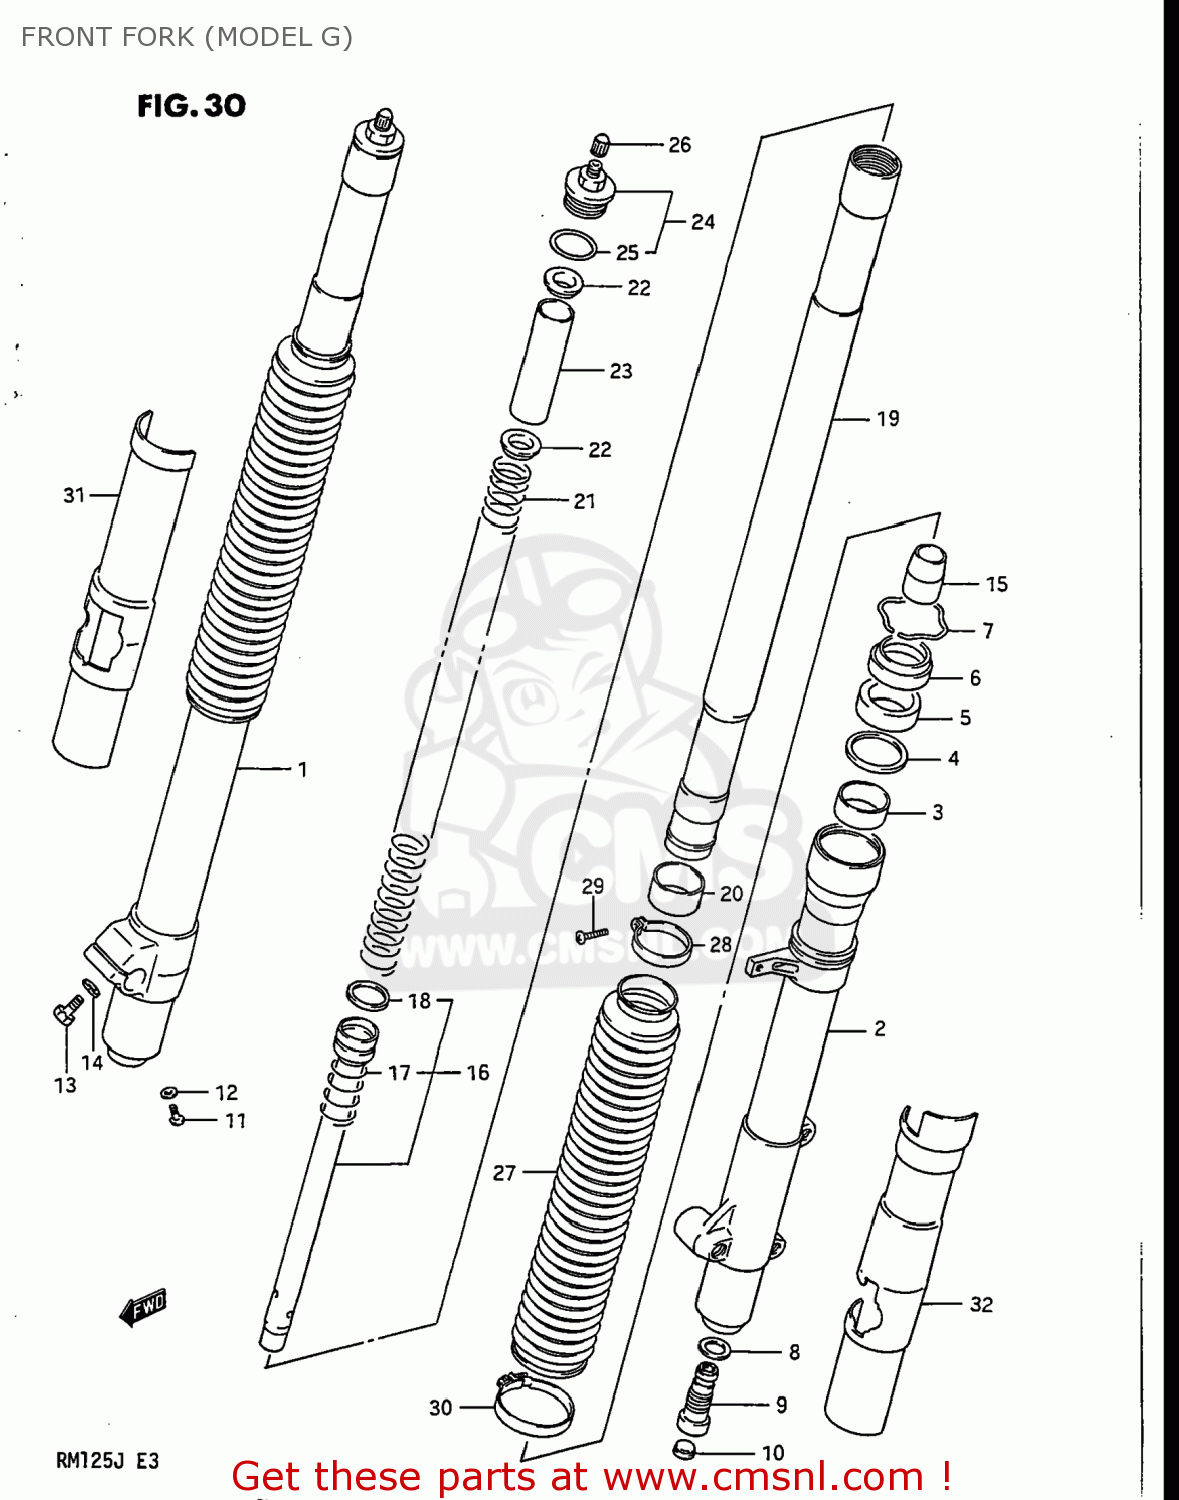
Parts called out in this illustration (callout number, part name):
1	TUBE,OUTER,RIGHT
2	TUBE,OUTER,LEFT
3	METAL,SLIDE
4	WASHER
5	SEAL,OIL
6	SEAL,DUST
7	RING,STOPPER
8	GASKET,FORK CYLINDER
9	VALVE,DF
10	CAP,FRONT FORK DF
11	SCREW 4X6
12	GASKET,DRAIN,PLUG (NAS)
13	BOLT
14	WASHER,LOCK,8.
15	PIECE,FRONT FORK OIL LOCK
16	CYLINDER,FRONT FORK
17	SPRING,REBOUND
18	RING,FRONT FORK PISTON
19	TUBE,FORK,INNER
20	PISTON
21	SPRING
22	GUIDE,FRONT FORK SPRING
23	SPACER,FRONT FORK SPRING
24	CAP,FORK INNER TUBE
25	O RING
26	CAP
27	BOOT
28	BAND,BOOT,UPPER
29	SCREW 4X10
30	BAND,BOOT LWR
31	PROTECTOR,RIGHT
32	PROTECTOR,LEFT
